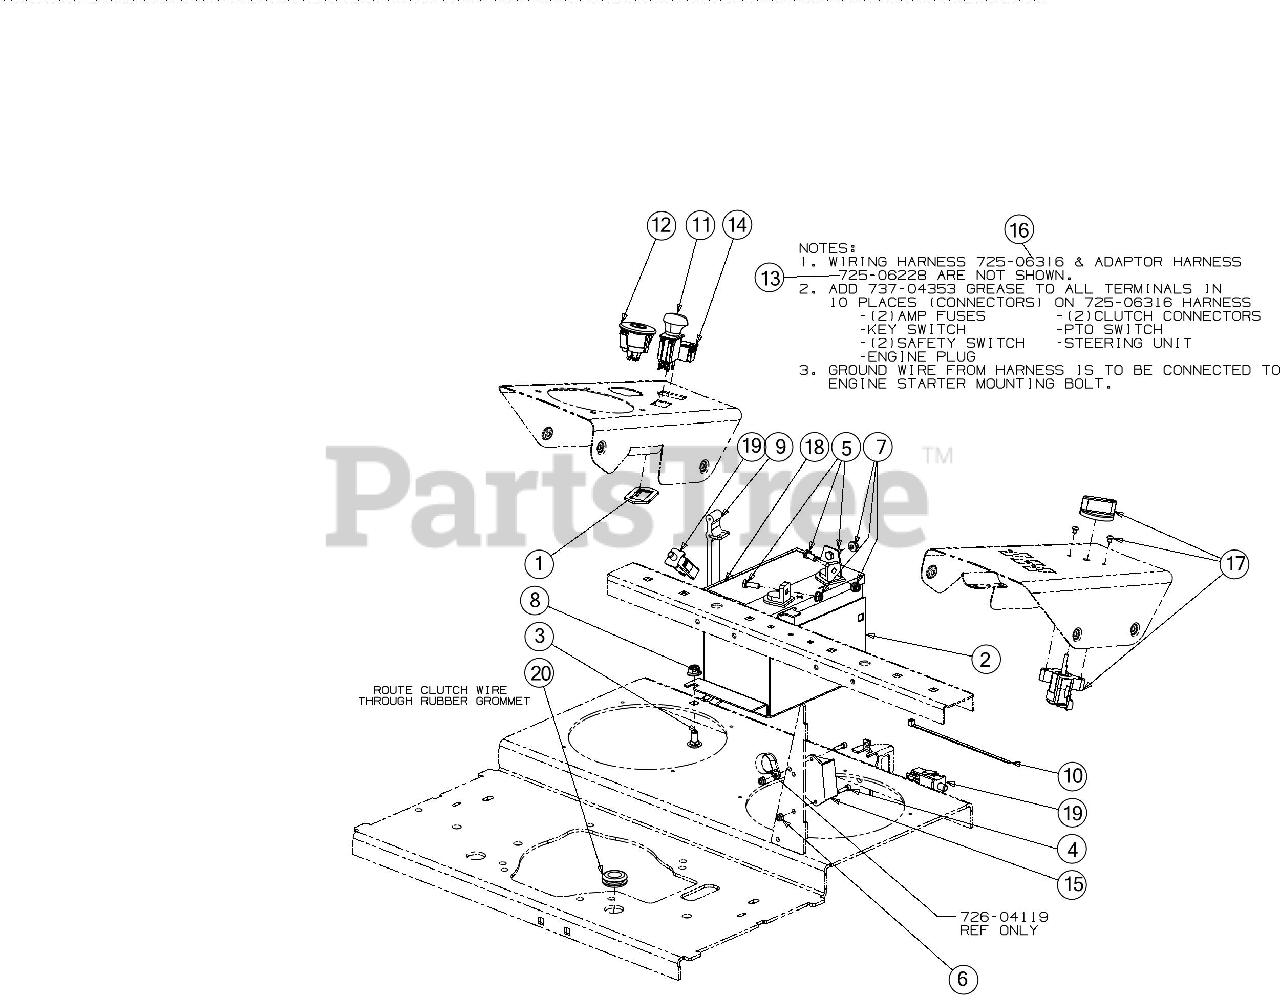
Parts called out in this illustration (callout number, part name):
1	BRACKET-PTO SWITCH
2	BATTERY BRACKET
3	CARRIAGE BOLT 3/8-16 x .750 GR5
4	SCREW 10-24 x .750
5	SCREW 1/4-20X.75 GR5
7	FLANGE LOCK NUT
9	BATTERY RETAINER STRAP
10	7" CABLE TIE
11	ELECTRIC PTO SWITCH
12	KEY SWITCH 3 POSITION
14	HOUR METER
15	CONTROL PANEL
16	MAIN WIRING HARNESS
17	THROTTLE SWITCH
19	PLUNGER SWITCH
20	RUBBER GROMMET
